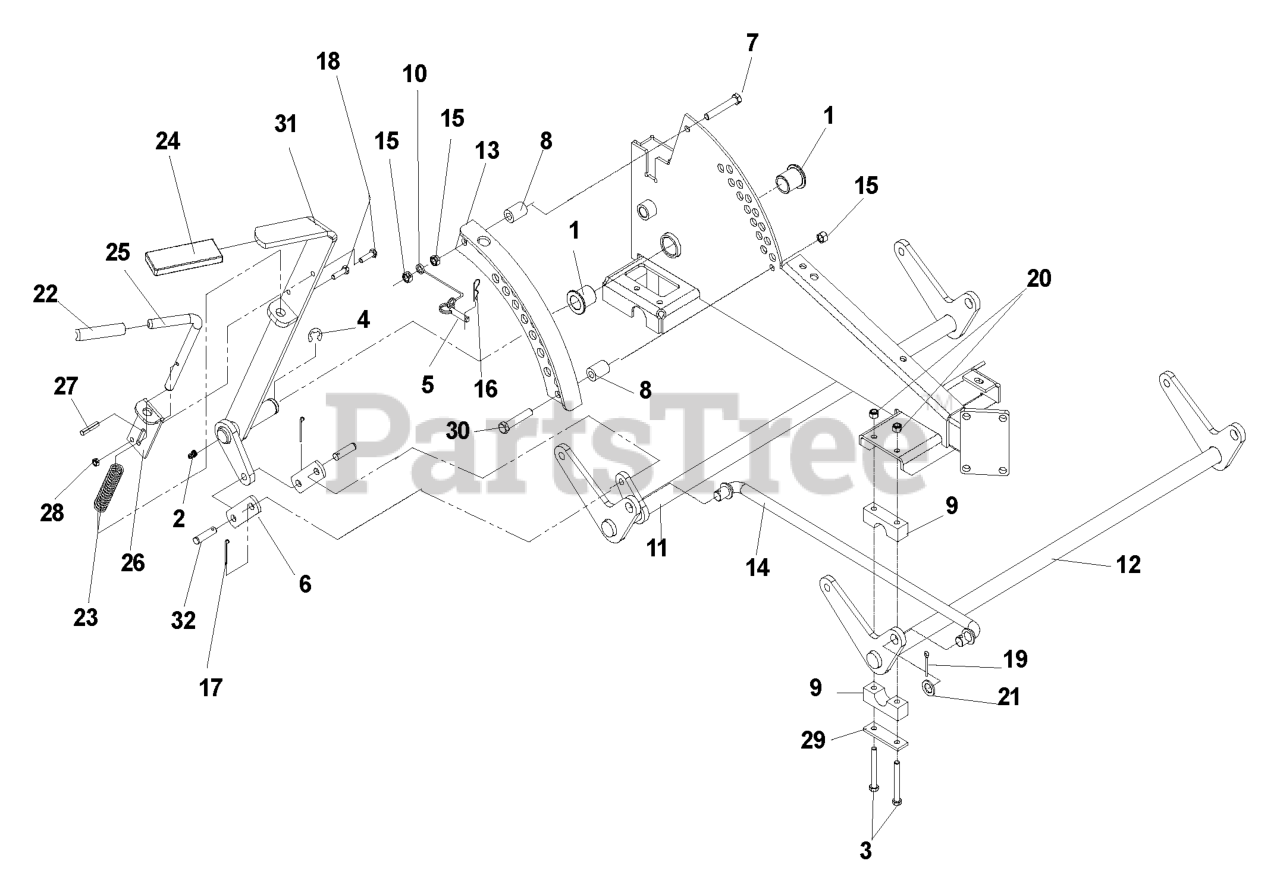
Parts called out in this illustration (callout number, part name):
3	HCS, 5/16-18 X 2 3/4, GR5
4	RING-E, 7/8
5	PIN LIFT, 1/2 X 2, W/RINGS
7	HCS, 3/8-16 X 2 3/4, GR5
9	BLOCK-PILLOW
11	REAR LIFT SHAFT
12	FRONT LIFT SHAFT
13	ADJUSTMENT PLATE
14	CROSS LINK
15	NUT, 3/8-16, NYLOC
16	PIN HAIR, .120 X 2 1/2
17	PIN COTTER
18	HCS,1/4-20 X 3/4, GR5
19	PIN COTTER, 5/32 X 1 1/4
20	NUT, 5/16-18, NYLOC
22	GRIP, VINYL
23	SPRING, COMPRESSION
24	GRIP, LIFT LEVER
25	PIN, 1/2 X 6.69 "L"
27	PIN GROOVED, 3/16 X 1 1/4
28	NUT, 1/4-20, CENTERLOCK
29	REINFORCED BAR
30	HCS, 3/8-16 X 2 1/2, GR5
31	LIFT LEVER
32	PIN CLEVIS, 3/8 X 1 1/8
